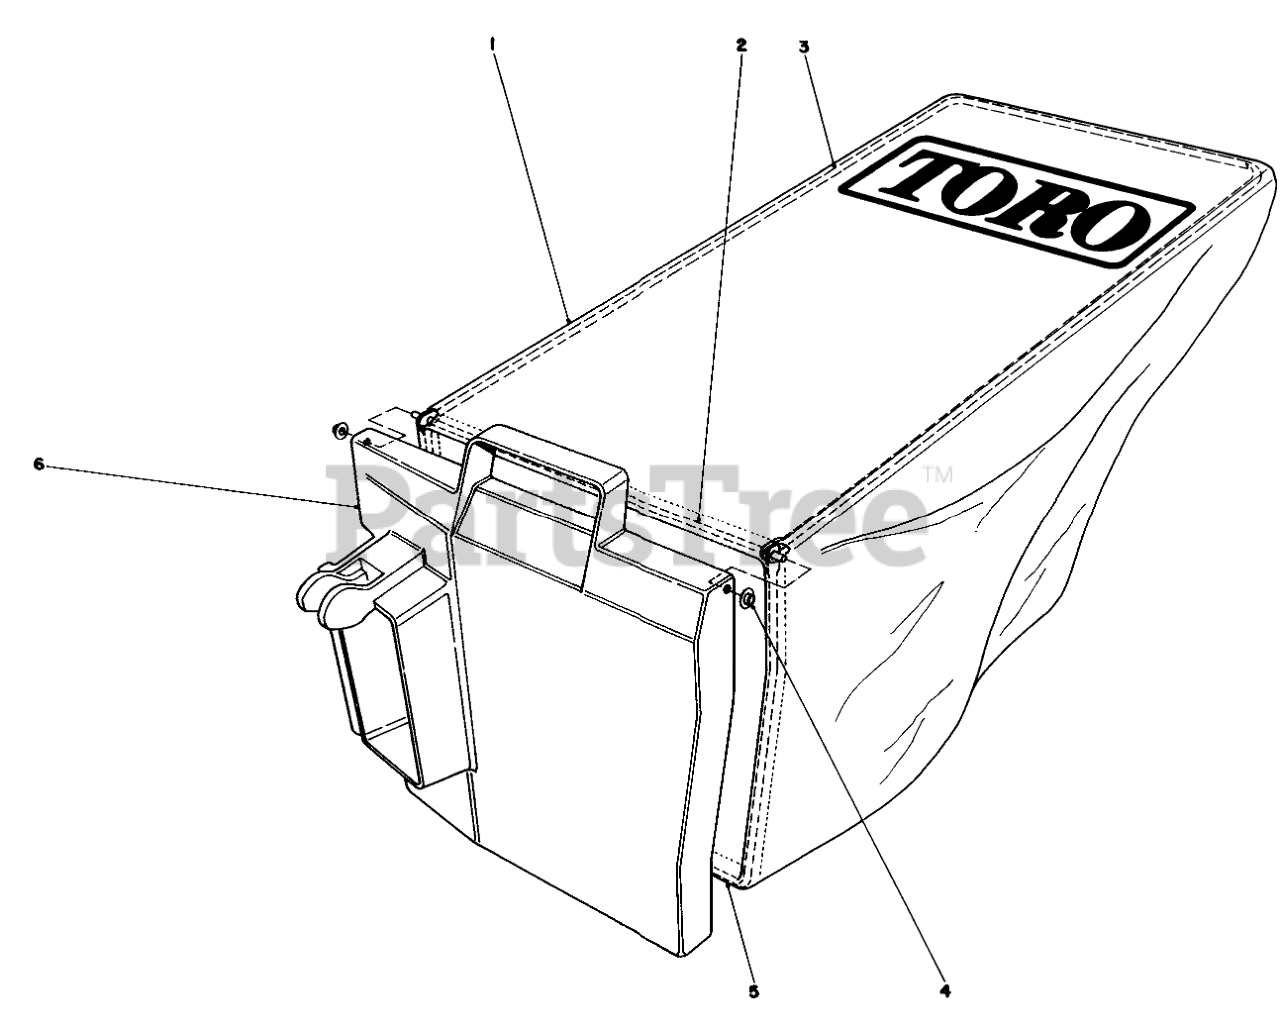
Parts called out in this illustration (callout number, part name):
1	18 BAGGER BAG 33-4552
2	HINGE PIN
3	BAG FRAME-UPPER
4	NUT-PUSH
5	Frame Bag
6	Door-Bag
